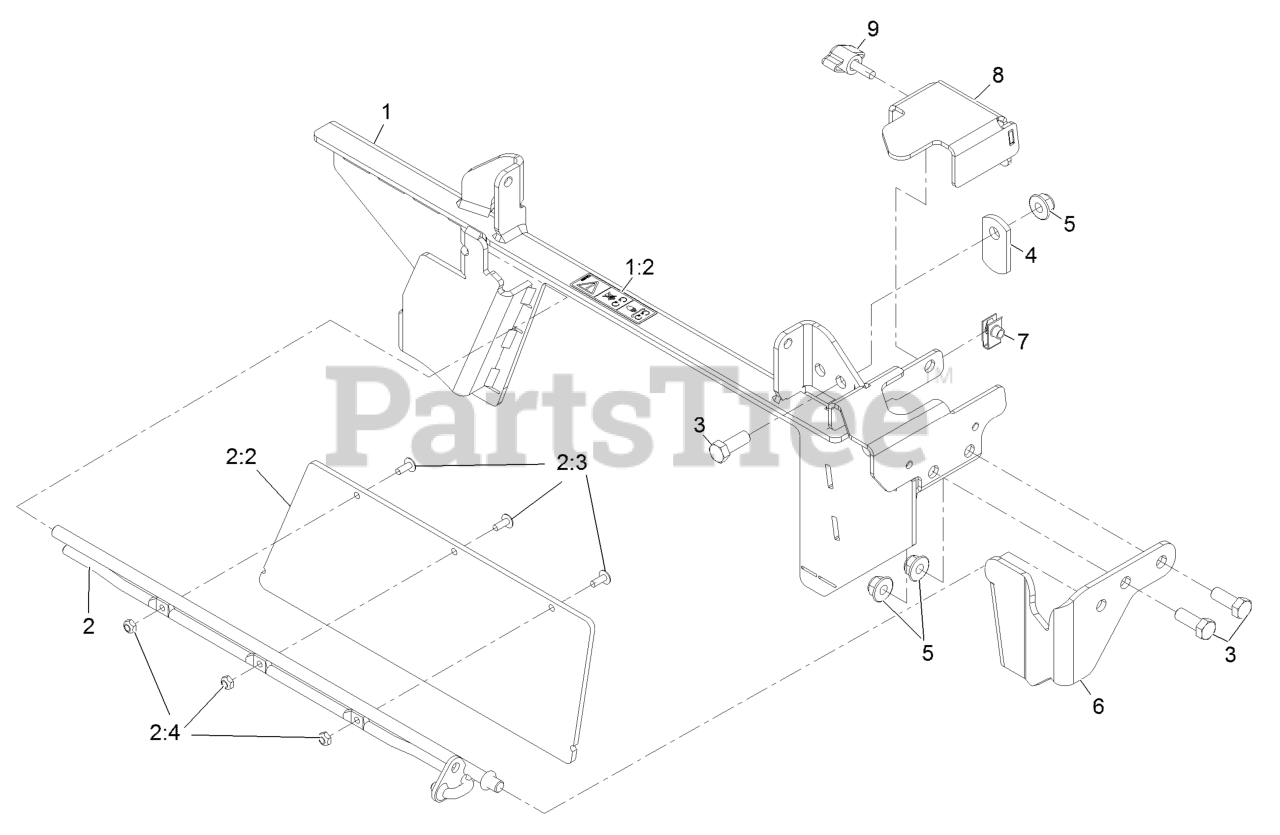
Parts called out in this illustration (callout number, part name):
1	OCD FRAME ASM W/ DECALS
1:2	DECAL, COVER MISSING
2	OCD GATE ASM
2:2	GATE-OCD
2:3	SCREW-PTH
2:4	NUT-LOCK, NI
3	SCREW-HH
4	LATCH-CATCHER, GRASS
5	NUT-HF, NI
6	BRKT,CHUTE FRONT
7	Nut-Retainer-Panel 1/4-20
8	BRACKET, CABLE MOUNT
